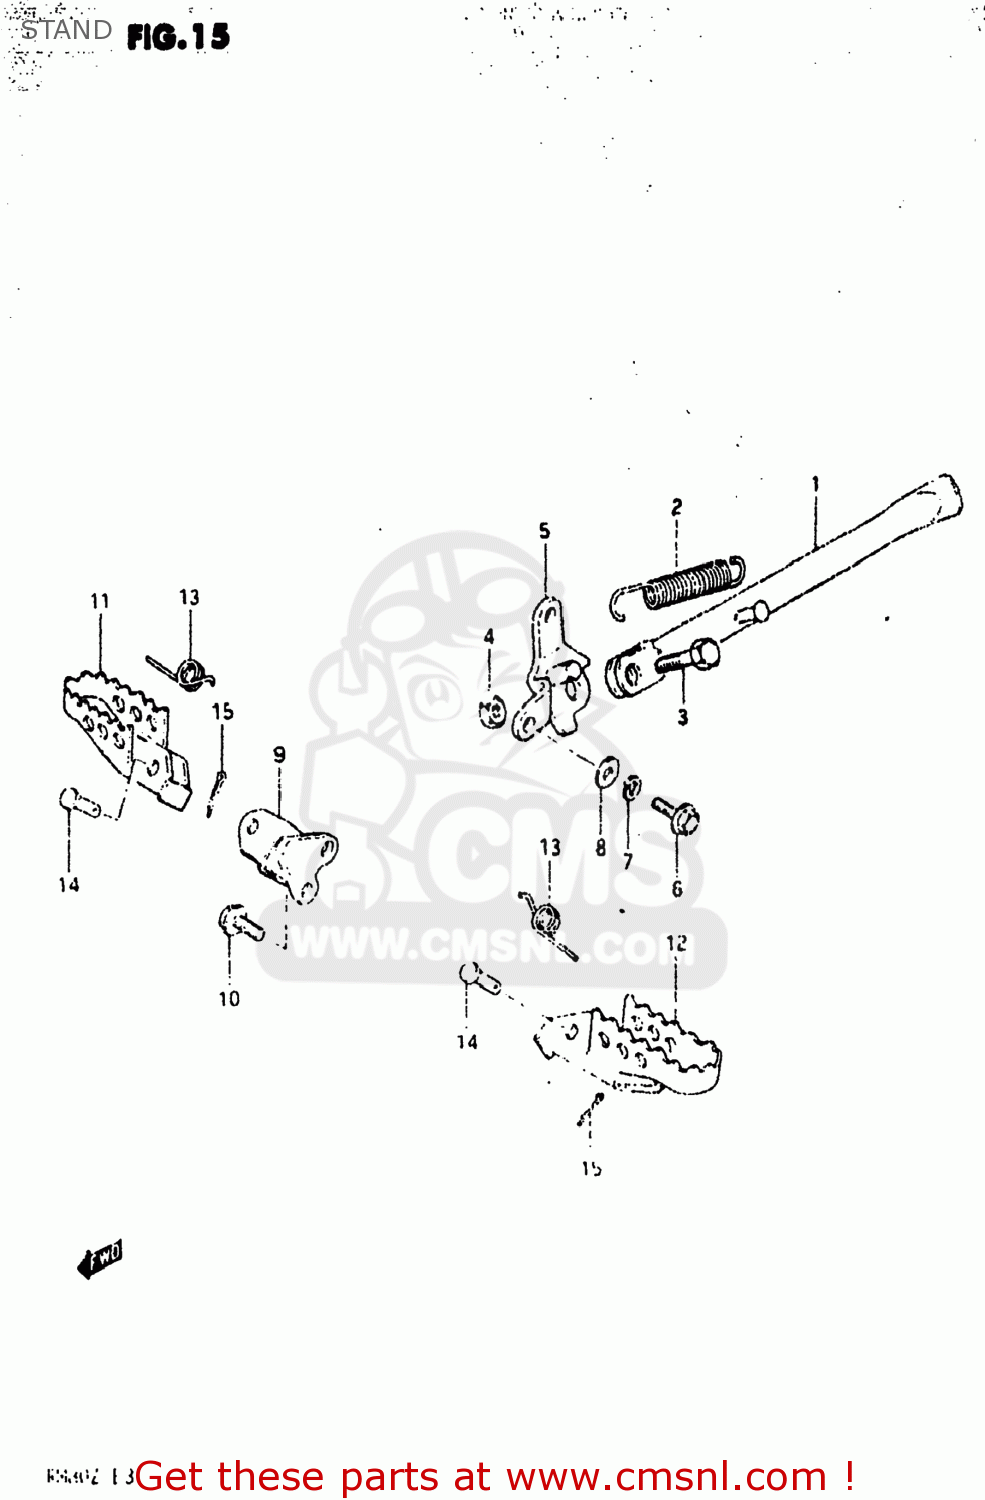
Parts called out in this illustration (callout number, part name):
1	STAND,SIDE
2	SPRING
3	BOLT
4	NUT
5	BRACKET,SIDE STAND
6	BOLT
7	LOCK WASHER
8	WASHER
9	BAR,FRONT FOOTREST
10	BOLT
11	FOOTREST,FRONT,RIGHT
12	FOOTREST,FRONT,LEFT
13	SPRING
14	PIN
15	PIN 20X20
